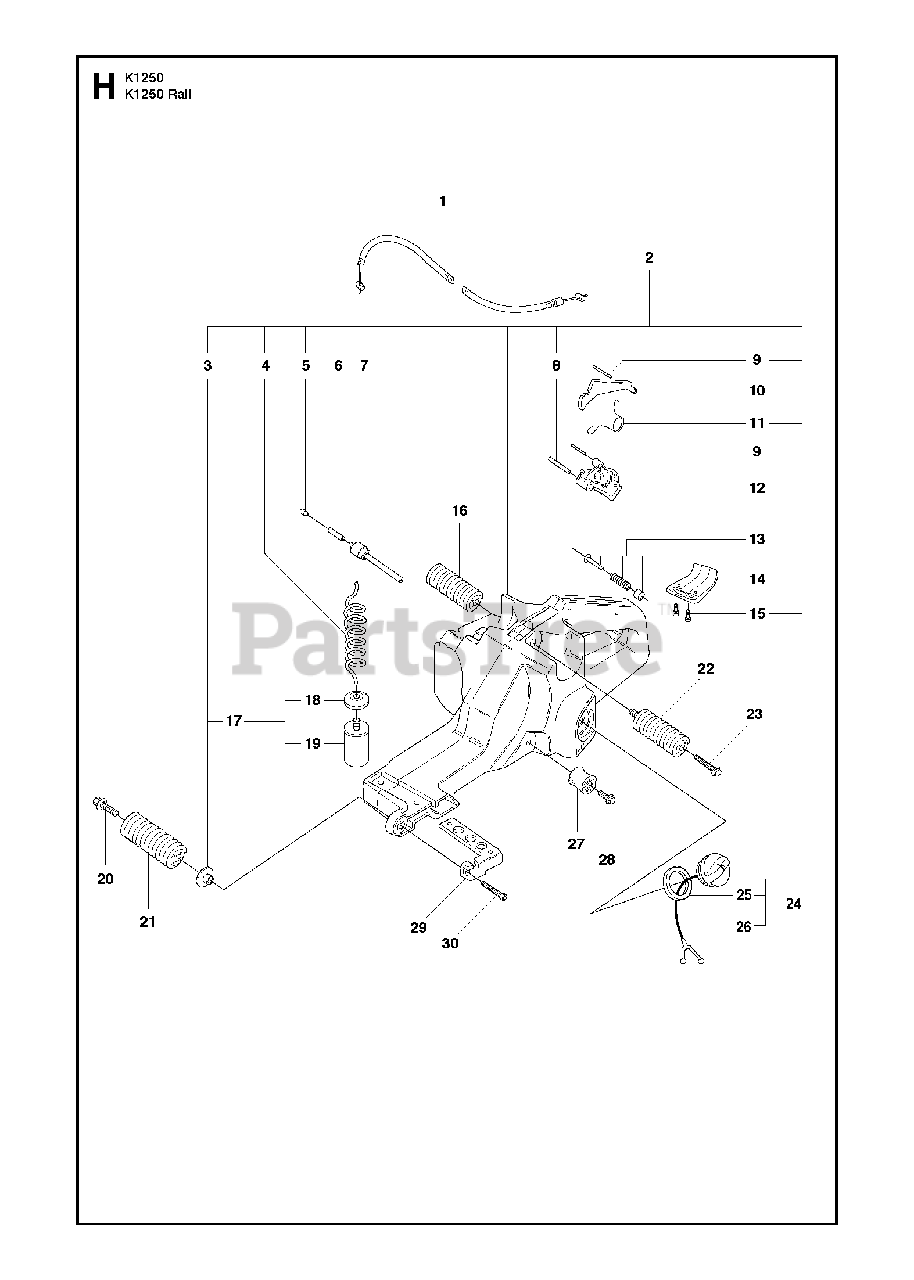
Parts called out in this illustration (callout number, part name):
1	THROTTLE CABLE ASSY
2	TANK UNIT ASSYIncl. 3 - 15, 17
4	FUEL HOSE
6	FUEL HOSE
7	TANK VENT
8	PARALLEL PIN
9	PARALLEL PIN
10	THROTTLE LOCKOUT
12	THROTTLE CONTROL ASSY
13	SPÄRRSTIFT RES
15	SCREW CRCSFT
16	ANTIVIBRATION ELEMENT
17	FUEL FILTERIncl. 18, 19
20	SCREW IHSCFM
21	ANTIVIBRATION ELEMENT
22	ANTIVIBRATION ELEMENT
24	TANK CAP ASSYIncl. 25, 26
27	ANTIVIBRATION ELEMENT
28	SCREW IHSCFM
29	STIFFENING PLATE
30	SCREW IHSCFM
